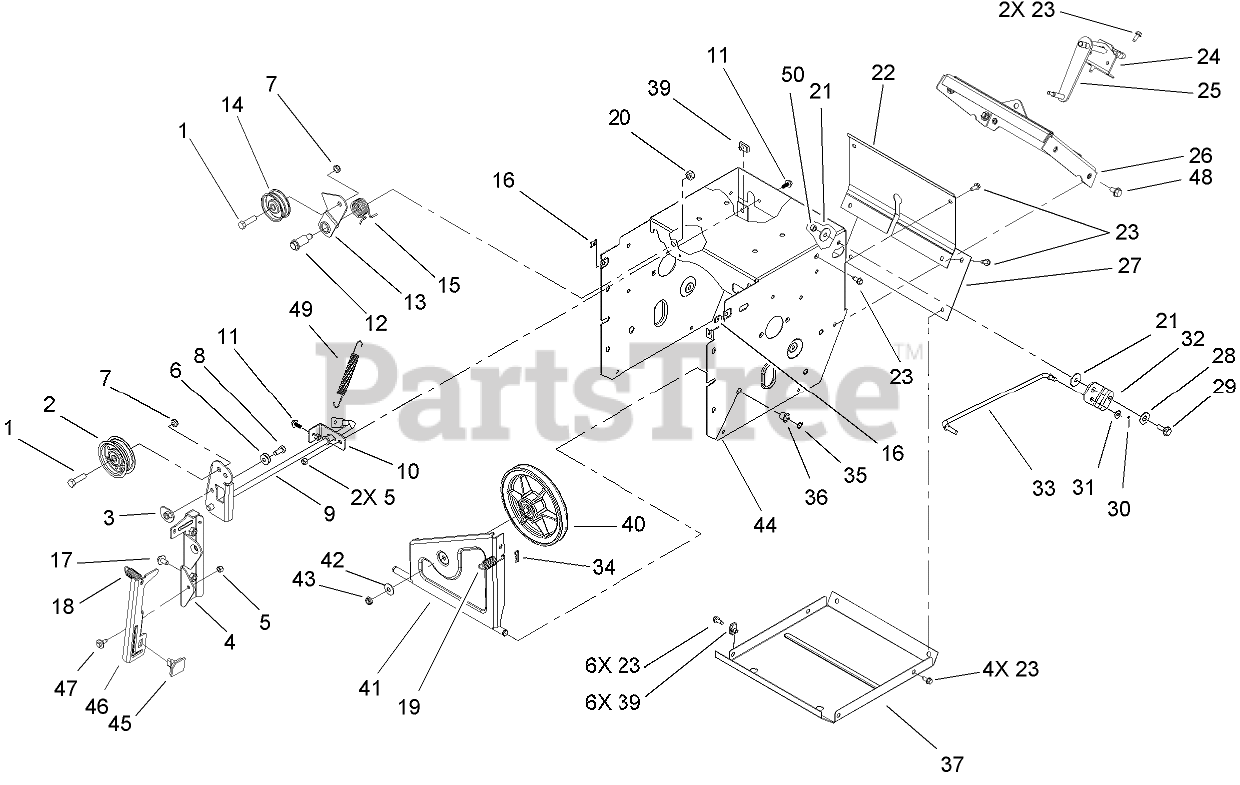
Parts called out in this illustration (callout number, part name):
1	SCREW-HH
2	PULLEY-IDLER
4	BRACKET-IDLER, IMPELLER
5	NUT-LOCK, NI
6	WASHER-BELLEVILLE
7	NUT-LOCK, NI
8	SCREW-HH
9	IMPELLER CLUTCH ASM
10	BRACKET-REAR, CLUTCH
11	SCREW-HHF
12	BOLT-SHOULDER
13	ARM-IDLER, TRACTION
14	PULLEY-IDLER
15	SPRING-TORSION
16	NUT-SPEED, U-TYPE
17	SCREW-HHF
18	SPRING-EXTENSION
19	SPRING-EXTENSION
20	NUT-LOCK, NI
21	WASHER-PIVOT
22	COVER-UPPER
23	SCREW-HWH
24	BRACKET-ROD, SHIFT
25	LEVER-CONTROL, TRACTION
26	SHIFT PLATE ASM
27	COVER-LOWER
28	WASHER
29	SCREW-SHOULDER
30	PIN-COTTER
31	WASHER-PLAIN
32	BELLCRANK-DRIVE
33	LINK-CONTROL, SPEED
34	PIN-COTTER
35	RING-RETAINING
36	BUSHING-NYLINER
37	PAN-BOTTOM
40	PULLEY-TRACTION
41	PULLEY PIVOT ASM
42	WASHER-BELLEVILLE
43	NUT-HEX
44	TRACTION FRAME ASM
45	PAD-BRAKE
46	ARM-BRAKE
47	SCREW-SHOULDER
48	SCREW-HWHTF
49	SPRING-EXTENSION
50	NUT-LOCK, NI
